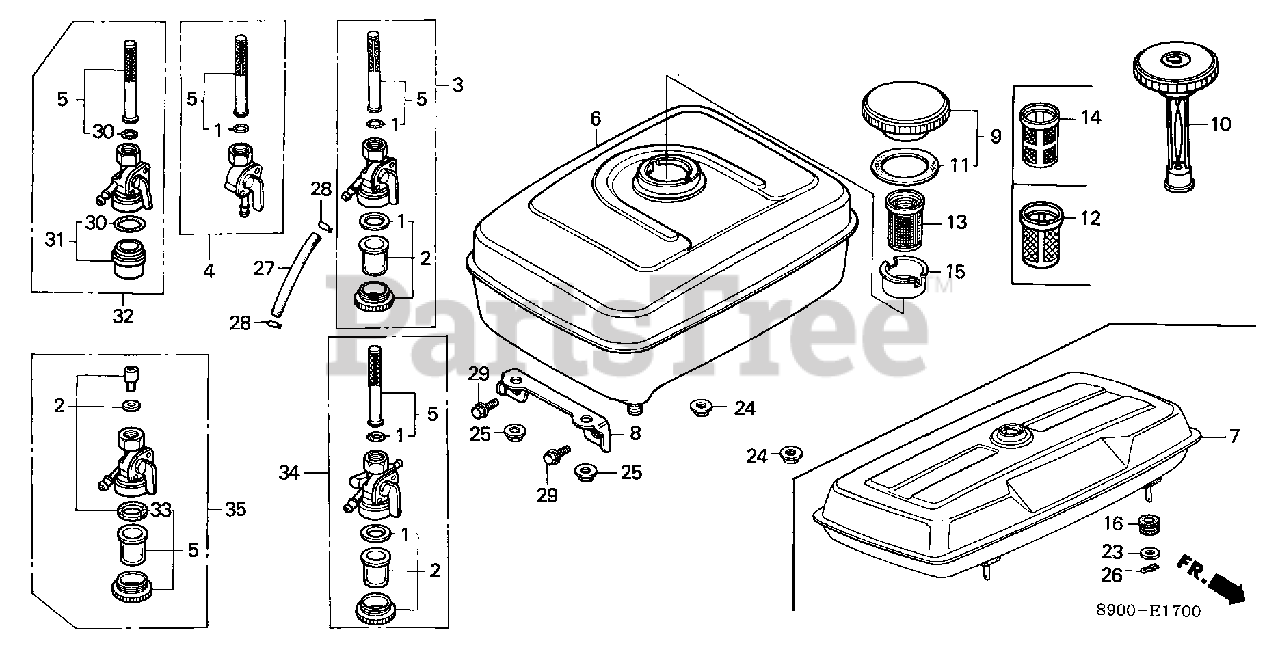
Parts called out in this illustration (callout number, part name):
1	GASKET SET, PETCOCK
2	CUP, FUEL STRAINER
2	CUP SET, FUEL STRAINER
3	PETCOCK ASSY.
4	PETCOCK ASSY.
5	SCREEN SET
6	TANK, FUEL *NH31* (MCKINLEY WHITE)
8	STAY, FUEL TANK
9	CAP, FUEL FILLER (BLACK)
10	GAUGE, FUEL (ENGLISH)
11	GASKET, FUEL FILLER CAP (39X58X3)
13	FILTER, FUEL
14	FILTER, FUEL
15	HOLDER, FUEL FILTER
24	NUT, FLANGE (8MM)
25	NUT, FLANGE (8MM)
27	BULK HOSE, FUEL (4.5X3000) (4.5X85)
28	CLIP, TUBE (B8)
29	BOLT, FLANGE (8X16)
30	O-RING (CONTAINS 1 LARGE & 1 SMALL. USE AS NEEDED)
31	CUP, FUEL STRAINER
32	PETCOCK ASSY.
33	GASKET SET, PETCOCK (NOT AVAILABLE)
34	PETCOCK ASSY. (NOT AVAILABLE)
35	PETCOCK ASSY.
